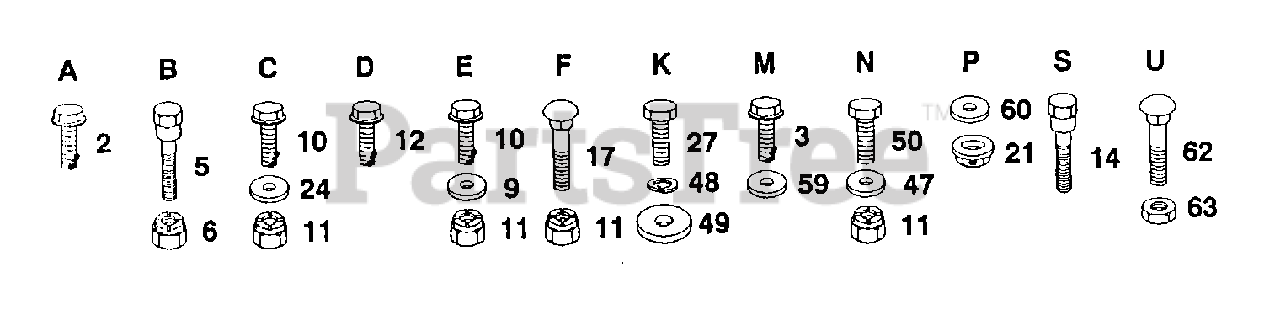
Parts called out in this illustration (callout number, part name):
2	SCREW
3	SCREW GTV
9	WASHER
12	SCREW LT
14	"BOLT,SHOULDER"
17	BOLT
21	PAL NUT LT
24	WASHER
27	BOLT
47	WASHER
48	LOCKWASHER
49	WASHER
50	BOLT
59	WASHER
60	WASHER PM
62	BOLT
